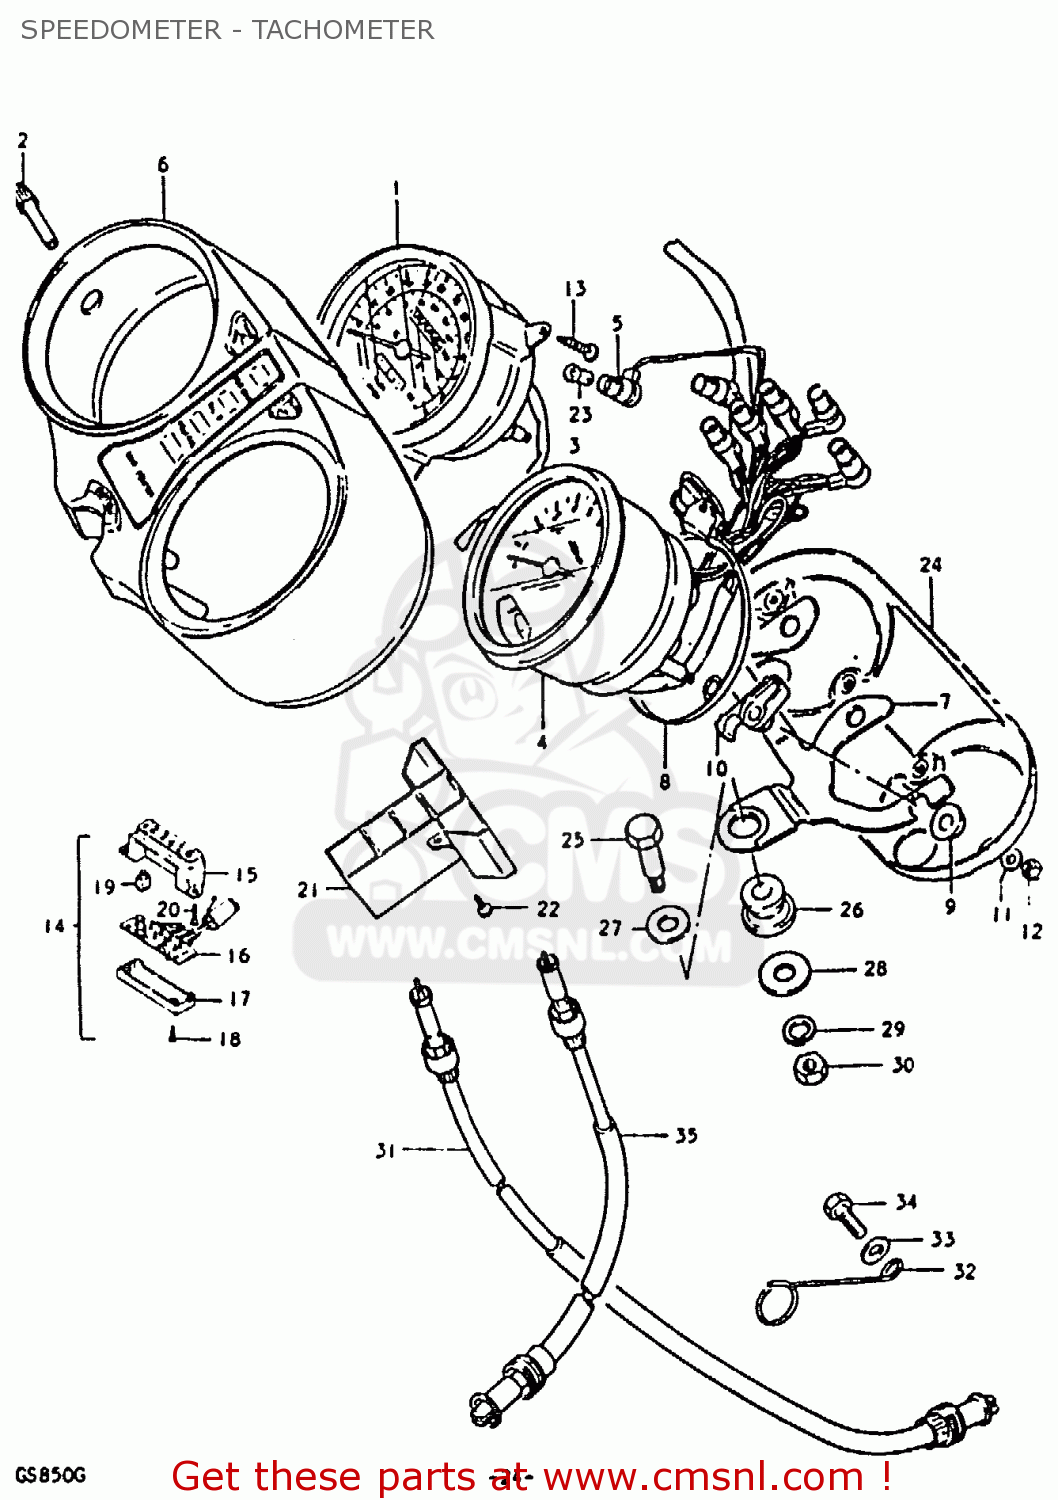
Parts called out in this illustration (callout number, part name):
1	SPEEDOMETER
2	KNOB
3	WIRE,LEAD
4	TACHOMETER
5	SOCKET,METER
6	CASE
7	BRACKET,COMBINATION METER
8	PLATE,METER,UNDER
9	CUSHION,METER (A)
10	CUSHION,METER (B)
11	WASHER
12	NUT
13	SCREW
14	INDICATOR ASSEMBLY,GEAR POSITION
15	CASE,GEAR INDICATOR
16	SOCKET,GEAR INDICATOR
17	COVER,LWR
18	SCREW,GEAR INDICATOR
19	BULB(14V1.12W)
20	SCREW
21	CASE,PILOT BULB
22	SCREW
23	BULB(12V3.4W,STANLEY,A72A)
24	COVER,UNDER
25	BOLT(8X31)
26	CUSHION,METER
27	WASHER
28	WASHER (8.5X29X1.6)
29	LOCK WASHER
30	NUT
31	CABLE ASSEMBLY,SPEEDOMETER
32	GUIDE,SPEEDOMETER CABLE
33	WASHER 6MM
34	BOLT, UPPER
35	CABLE ASSEMBLY,TACHOMETER
